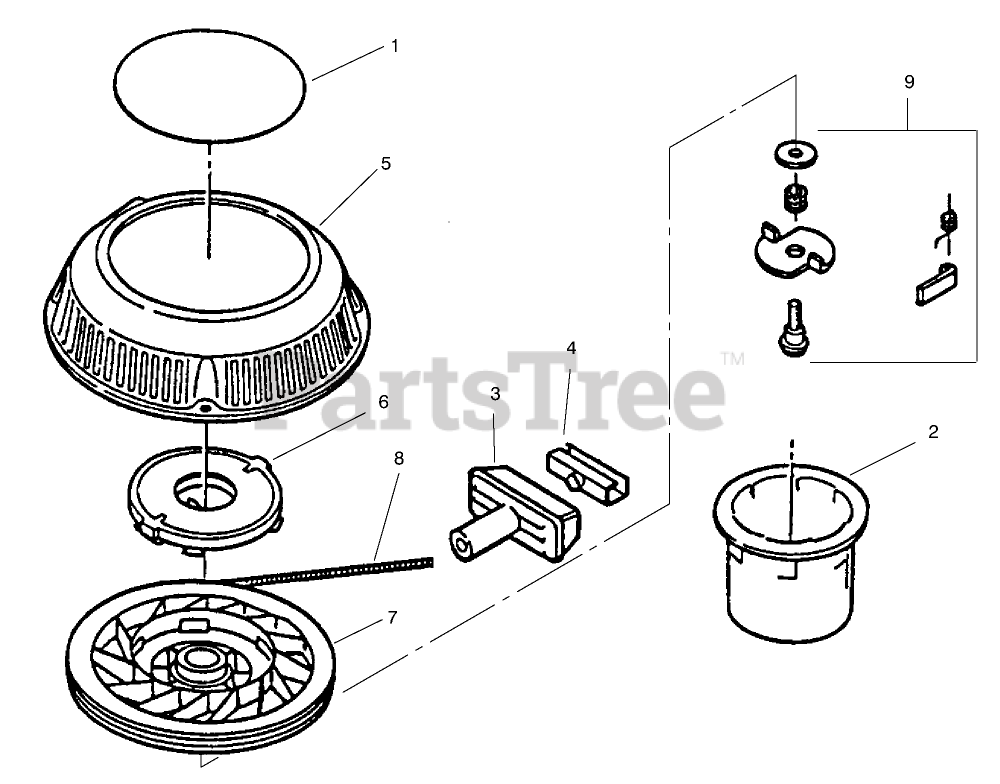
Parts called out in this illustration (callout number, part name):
1	DECAL - RECOIL
2	HUB-STARTER E COMM.
3	HANDLE-START
4	CLIP-STARTER
5	STARTER HOUSING & SHAFT
6	SPRING KEEPER ASM
7	PULLEY
8	ROPE-RECOIL
9	DOG KIT
